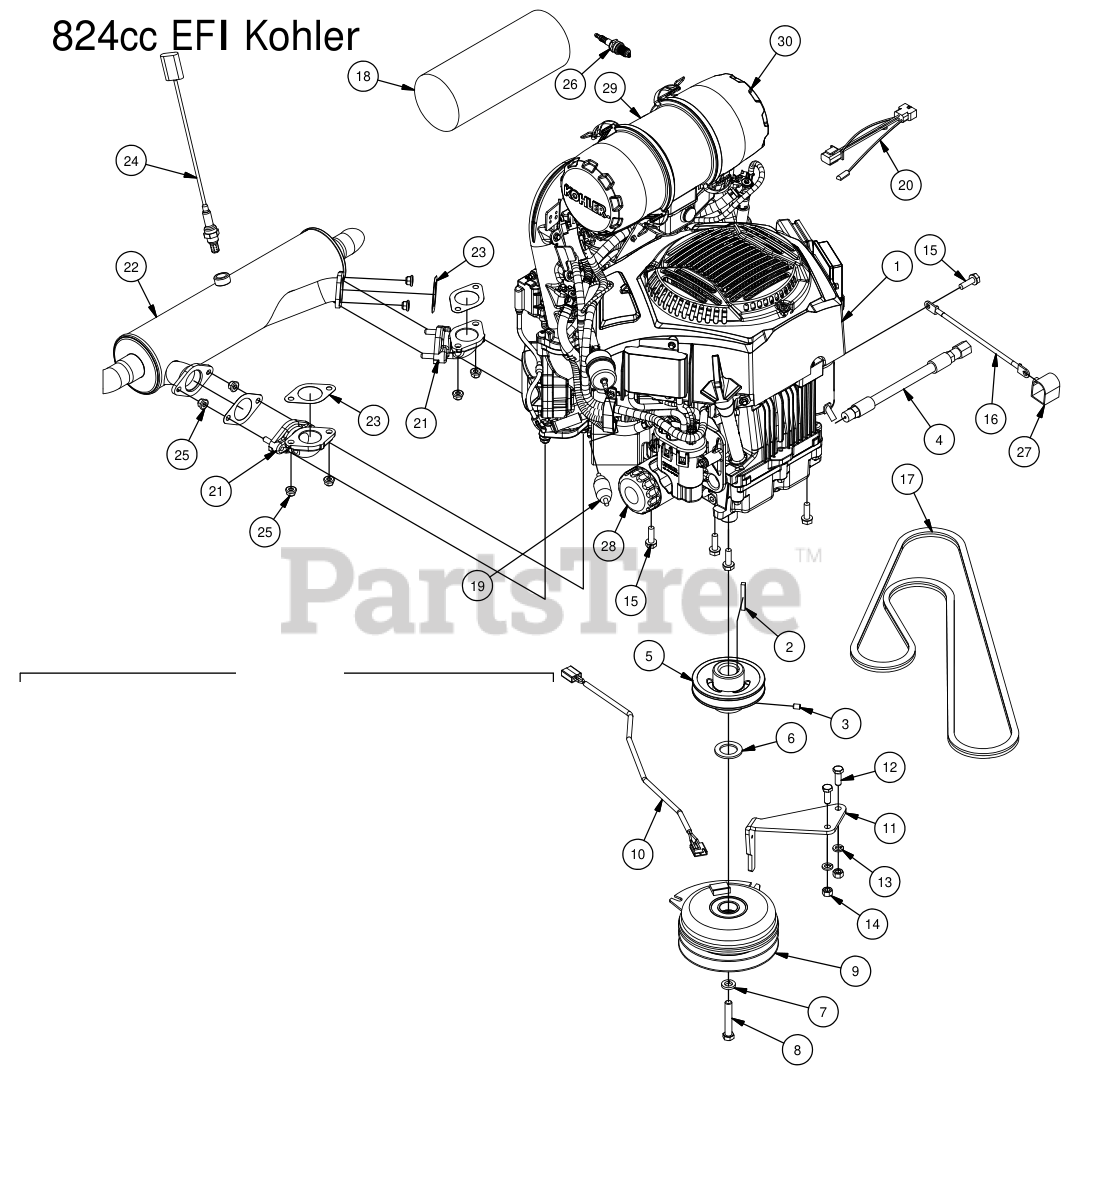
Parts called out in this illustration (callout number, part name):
1	824cc EFI Kohler
2	1/4 x 2 Square key Stock
3	3/8" Set Screw
4	Oil drain Hose
5	4 3/4 Motor Pulley
6	1 1/8" Flat Spacer
7	7/16" Lock Washer
8	7/16" x 2 1/2" Hex Bolt
9	Clutch Assembly
10	Clutch Pigtail
11	PTO Engager Holder
12	3/8" x 1" Hex Bolt
13	3/8" Lock Washer
14	3/8" Hex Nut
15	3/8 x 1 1/8 bolt
16	Ground Cable
18	Canister Air Filter- Outer
19	25/26 HP Kohler Fuel Filter
20	Harness Adaptor - 824cc EFI Kohler
21	Cast 90 Elbow
22	824cc Kohler Exhaust
23	Exhaust Gasket for 824EFI Kohler
24	02 Sensor for 824EFI Kohler
25	M8.125 Mechanical locking Flange Nut
26	Spark Plug - Kohler EFI
27	Black Boot For Ground Cable
28	Oil Filter
29	Kohler Air Canister Complete
30	Kohler End Cap
